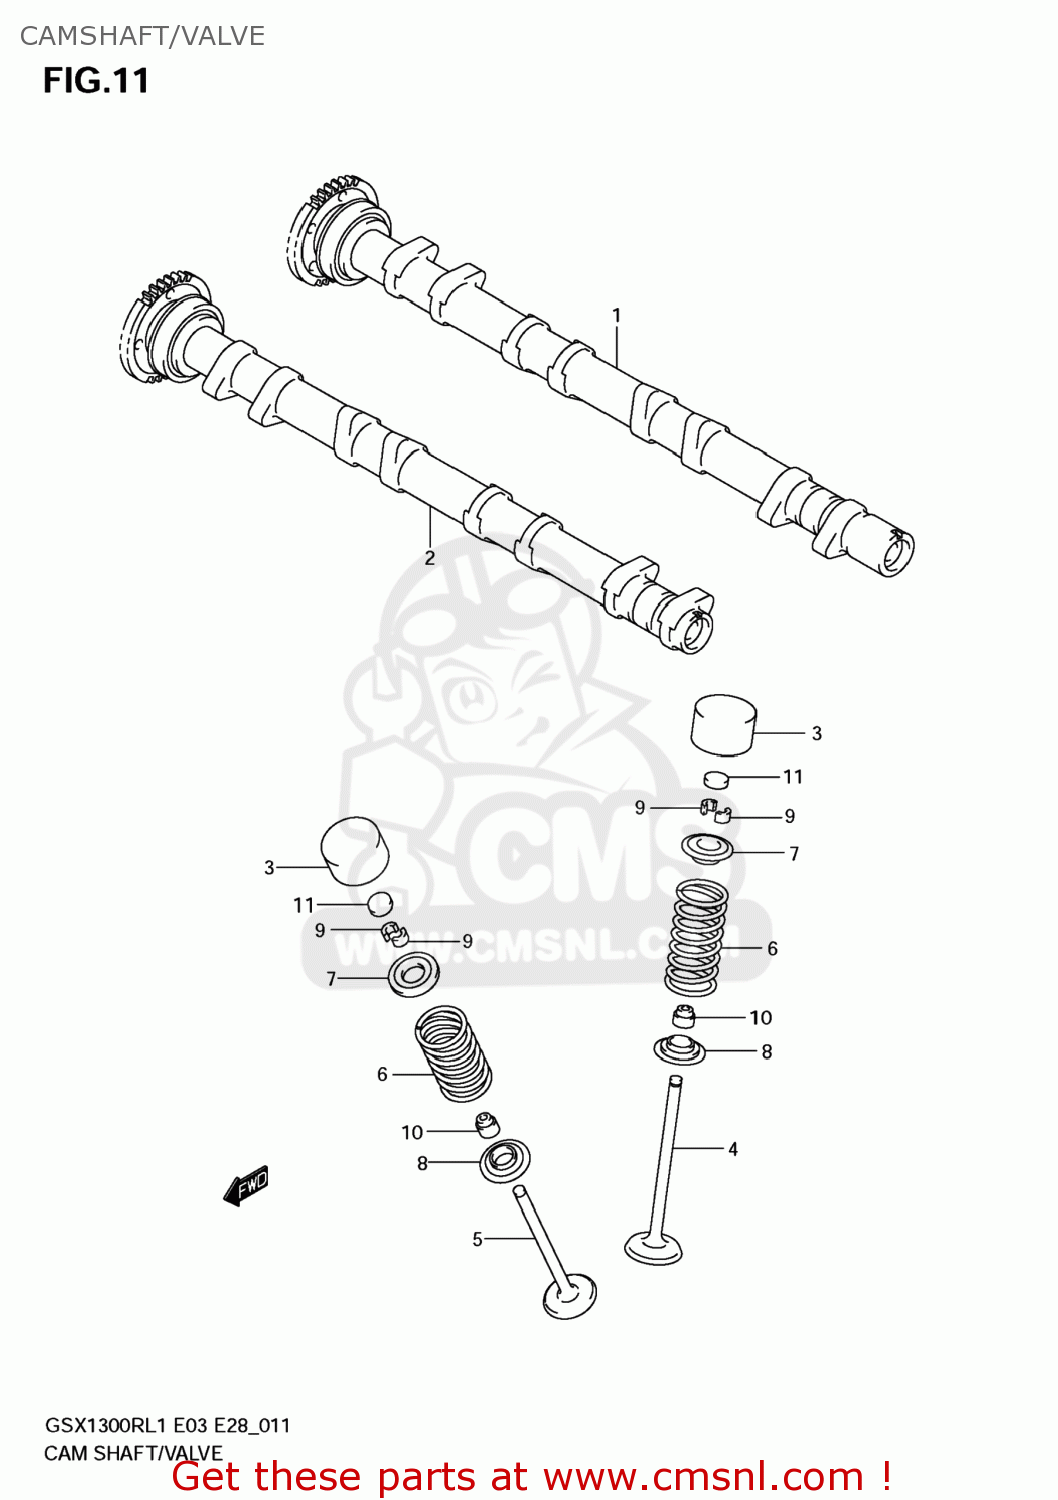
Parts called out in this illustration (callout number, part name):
1	CAMSHAFT,INTAKE
2	CAMSHAFT,EXHAUST
3	TAPPET
4	VALVE,INTAKE
5	VALVE,EXHAUST
6	SPRING,VALVE
7	RETAINER,VALVE SPRING
8	SEAT,VALVE SPRING
9	COTTER VALVE
10	SEAL,OIL(5X10X9.7)
11	SHIM,TAPPET
12	SHIM SET,TAPPET
13	CASE,TAPPET SHIM
